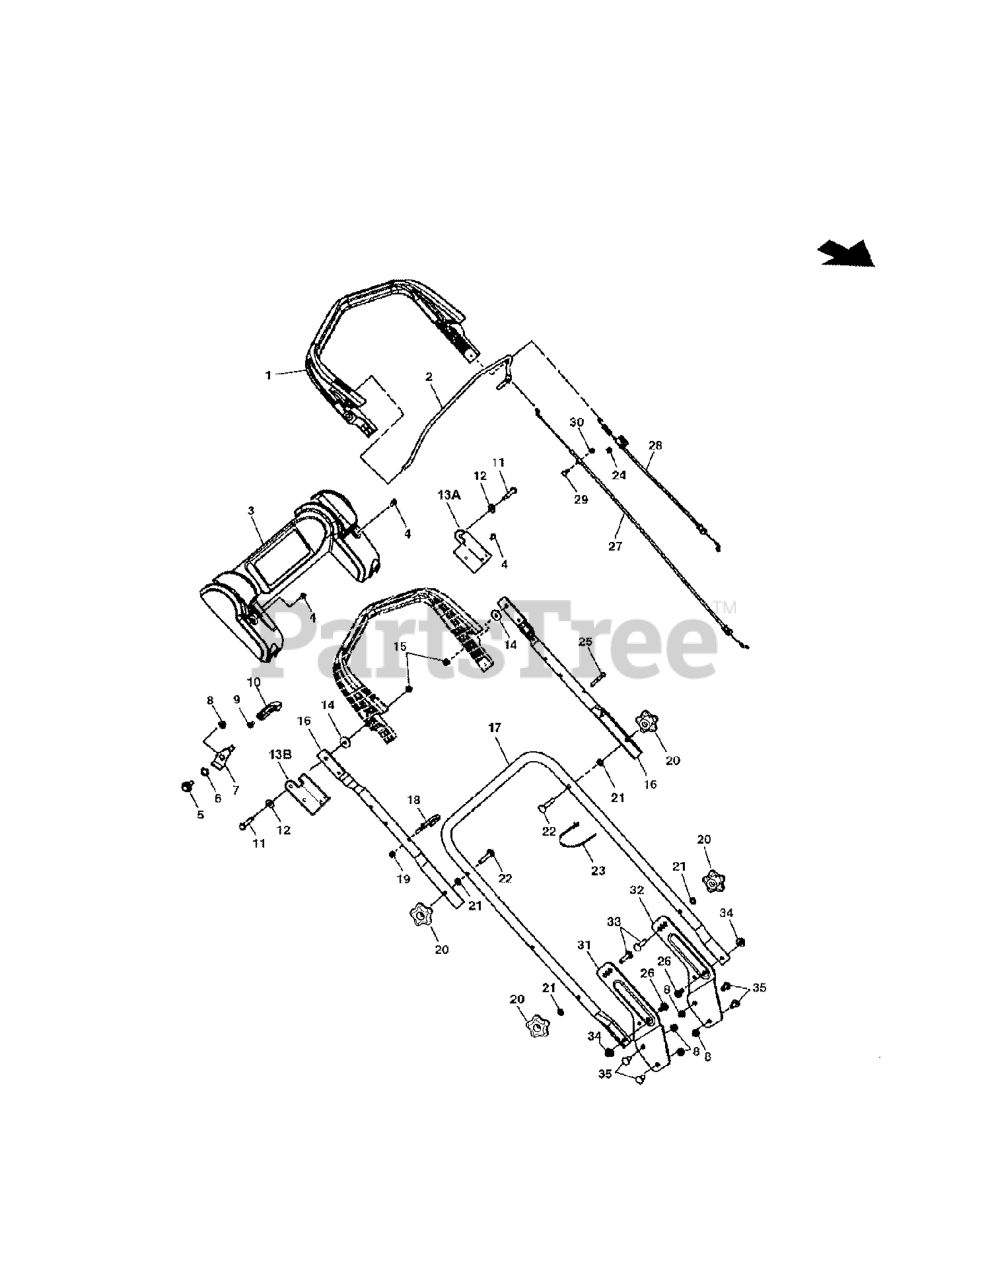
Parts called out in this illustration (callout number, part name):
1	HANDLE, PIVOTING - DEERE WALK
2	BAIL, PIVOTING HANDLE - 21" JD WBM
3	PANEL, UPPER HANDLE, DEERE
4	TORX ST, 1/4-20 X .550
5	IDLER PIVOT BOLT
6	WASHER , .531 X .781 3-WAVE
7	HANDLE, LOCK
8	FLN, 5/16-18 YZ
9	RIVET, PLASTIC SNAP
10	THROTTLE CONTROL LEVER
11	BOLT, SHOULDER, 5/16 X 2.500, YZ
12	SHIM WASHER, 5/16 I.D.
13A	BRACKET, LH, ROTATION LIMIT
13B	BRACKET, RH, ROTATION LIMIT
14	WASHER, FLAT, 1" OD X .387 ID
15	NUT, HEX FLANGE, 1/4-20, ESNA,YZ
16	HANDLE, UPPER, STRAIGHT, EASY LINE
17	HANDLE, LOWER 21" RD, JD
18	GUIDE, ROPE
19	HN, 1/4C NYL RNG
20	KNOB, HANDLE, 5 PRONG
21	ITLW, 5/16
22	CHSNB, 5/16-18 X 2 GR2
23	WIRE TIE,11 INCH STD BLK NYLON
24	HCLN, 1/4-20
25	HHCS, 1/4CX1-3/4
26	RHSSNB, 5/16-18 X 3/4 GR5 BZ
27	CABLE, CONTROL, ZONE
28	CABLE, DRIVE, 21" WBM, RD, DEERE
29	RHSNB, 10-24X3/4, YZ
30	HLN, 10-24 UNC-2B W/NYLON INSERT
31	BRKT, LOWER HANDLE, RH, JD 21" WBM, RD
32	BRKT, LOWER HANDLE, LH, JD 21" WBM, RD
33	BOLT, RD HD SH SQ NK 5/16-18X1.500 G5 YZ
34	LHCLN, 5/16-18- BLACK
35	RHSSNB, 5/16-18 X 3/4 GR5 YZ
